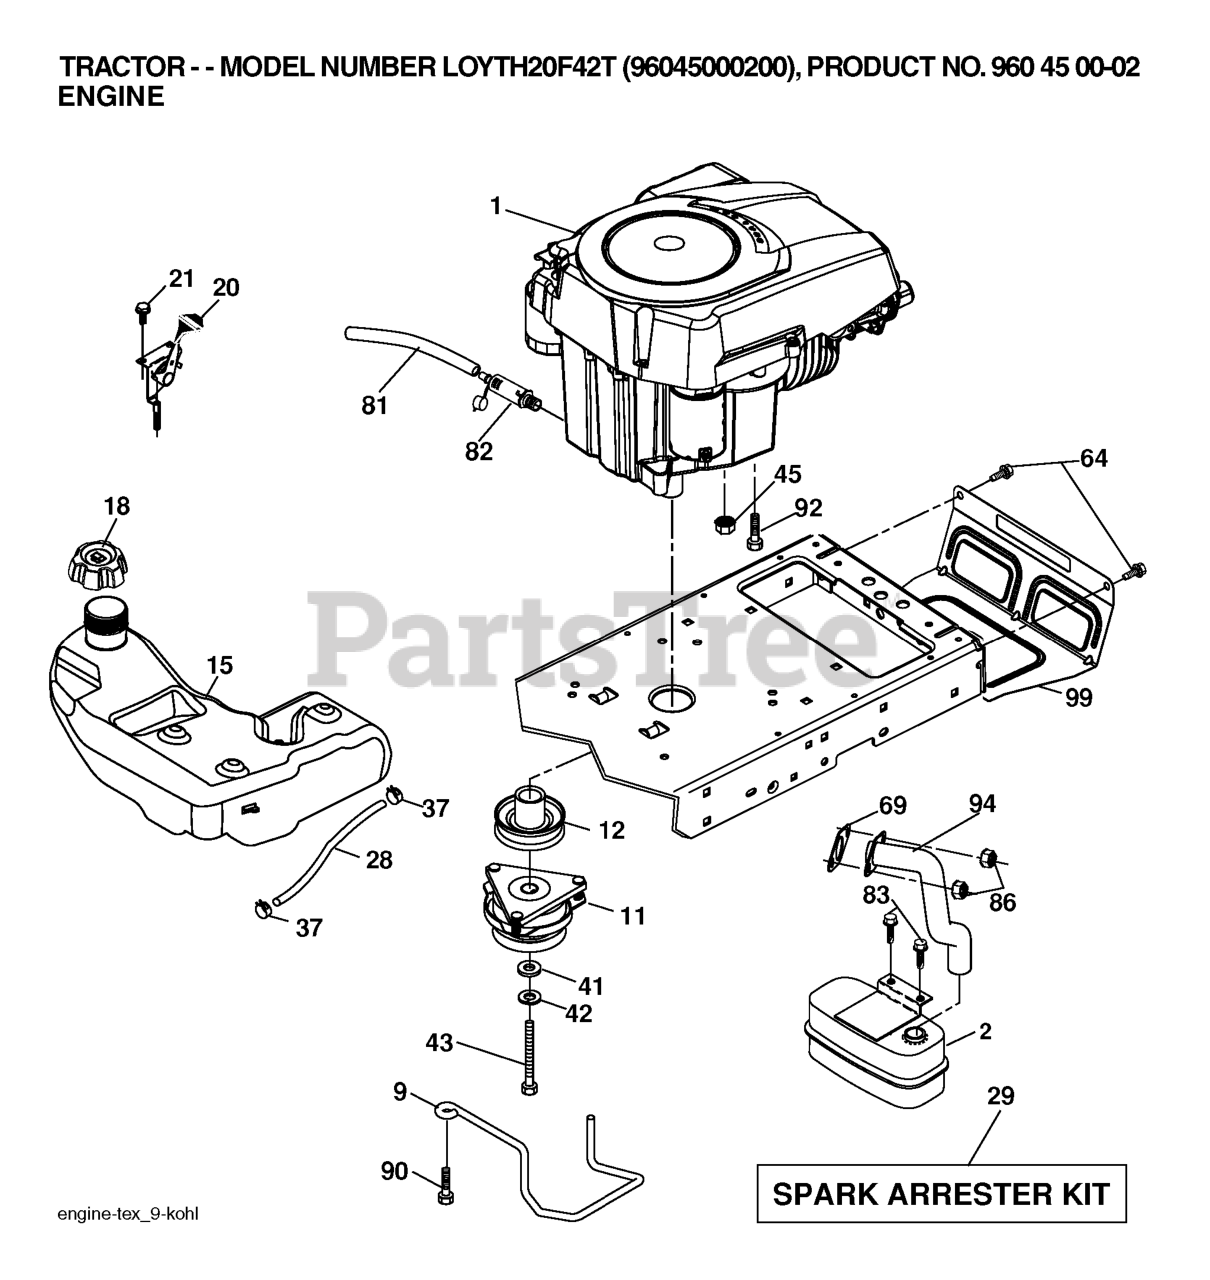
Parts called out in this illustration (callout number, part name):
2	MUFFLER.SINGLE.CYL.KOHL/B&S
9	KEEPER.BELT.ENGINE.3.25 (3 2)
11	RB.CLUTCH.OGURA.4.4.PD
12	PULLEY.ASM.ENG.OGURA.3
15	TANK.FUEL.4GAL
18	CAP.FUEL.TANK.3"GREY
20	CONTROL.TH/CK.COBRA.KO
21	SCREW
28	LINE.FUEL.64"REAR.EMIS
29	KIT.SPARK ARRESTOR 794945 B&S
37	HOSE CLAMP
42	LOCKWASHER
43	BOLT HEX 7/16-20X4-1/4"
45	NUT
64	SCREW, 3/8-16X3/4
69	GASKET.EXHAUST.KOHLER
81	TUBE, DRAIN OIL ASM.
82	PLUG DRAIN OIL EASY
83	BOLT.5/16-18UNCX3/4 W/SEMS.BLK
86	NUT.HEX.FLANGE.TOPLOCK
90	SCREW 3/8-16X1
92	SCREW 3/8-16X1
94	RP.TUBE.EXHAUST.KOHL.COURAGE
99	SHIELD.BROWNING/DEBRIS
